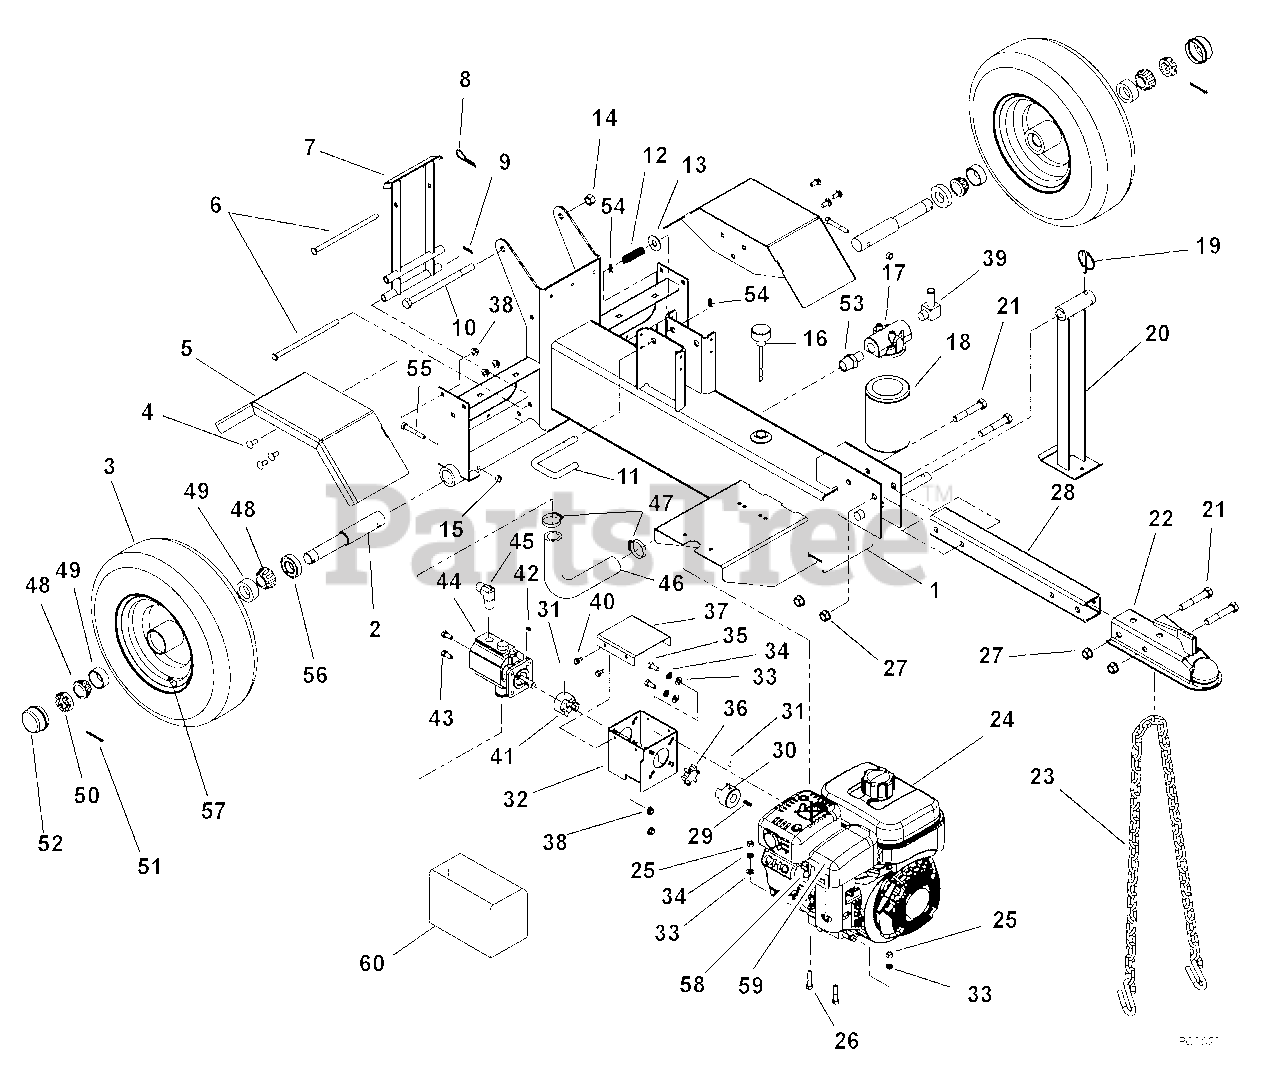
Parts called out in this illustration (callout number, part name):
1	CHASSIS,SPLITTER W/SAFTY DECAL
2	AXLE, SPLITTER
3	WHEEL, SPLITTER
4	@BLT-RDHDSQNK .31-18X.75 G5YZ
5	WLDMT, FENDER
6	PIN, LOCK
7	REAR STAND W/DECALS (ARIENS)
8	HAIRPIN, #7 CLIP .094X2.31 YWZ
9	PIN-HAIR, ENDRIES #25 YWZC
10	@BLT-HEX .50-13X7.50 GR5 YWZC
11	LOCK, BEAM
12	SPRG, COMP .058X.65X2.13 WLD15
13	@WSHR-FL-STL.563X1.38X.109YWZC
14	@NUT-LK-CTR .50-13 YWZC
15	@NUT-LK-CTR .31-18 YWZC
16	BREATHER, DIPSTICK
17	ASM, FILTER HEAD
18	FILTER ELEMENT, ZINGA AE-25
19	PIN-LOK .31X1.75
20	WMT,JACK
21	@BLT-HEX .50-13X3.00 GR5 YWZC
22	HITCH, BALL-2"
23	CHAIN, SAFETY
24	ENGINE,SUBARU 6HP SP170 (CARB)
25	@NUT-HEX .31-18 YWZC
26	@BLT-HEX .31-18X1.50 GR5 YWZC
27	@NUT-LK-CTR .50-13 YWZC
28	HITCH BAR W/DECALS
29	KEY-SQ .188X.75X.188
30	HUB,DRIVE COUPLING 3/4"
31	SCR-SET .25-20X.38 SKHCUPNL OH
32	WLDMT, PUMP MOUNT BRKT
33	@WSHR-FL-STL.344X.688X.065YWZC
34	WSHR-LK .312X.097 HVY YWZC
35	BLT-HEX .31-24X.75 YWZC GR5
36	SPIDER,URETHANE
37	COVER W/DECALS
38	@NUT-LK-TOP-FLG .31-18 YWZC
39	FTG,HYD 4501-10-12-FG
40	SCR-TAP .25-20X.50 HWH TR YWZ
41	HUB,DRIVE COUPLING 1/2"
42	KEY-WDRF .125X.50X.20 (HRDEND)
43	@BLT-HEX .31-18X.75 GR5 YWZC
44	PUMP, SPLITTER-11 GPM
45	FTG,HYD 2501-8-8
46	HOSE,HYD SUCTION 16G4H X 13.5
47	CLAMP-HOSE 1.50X.81X1.42
48	BRG, CONE W/ GREASE
49	BRG-CUP1.980X.420
50	NUT-SL 1.0-14
51	@PIN-CTR .15X1.50 YWZC
52	CAP,DUST
53	FTG,HYD 5404-12-12
54	CLIP, SPRING
55	@BLT-HEX .31-18X2.25 GR5 YWZC
57	VALVE STEM ASS'Y
58	SPARK PLUG,SP-170
59	FILTER,SP-170 SPONGE/ROBIN
60	OIL, 2.5 GAL HYD ISO GRADE 32
